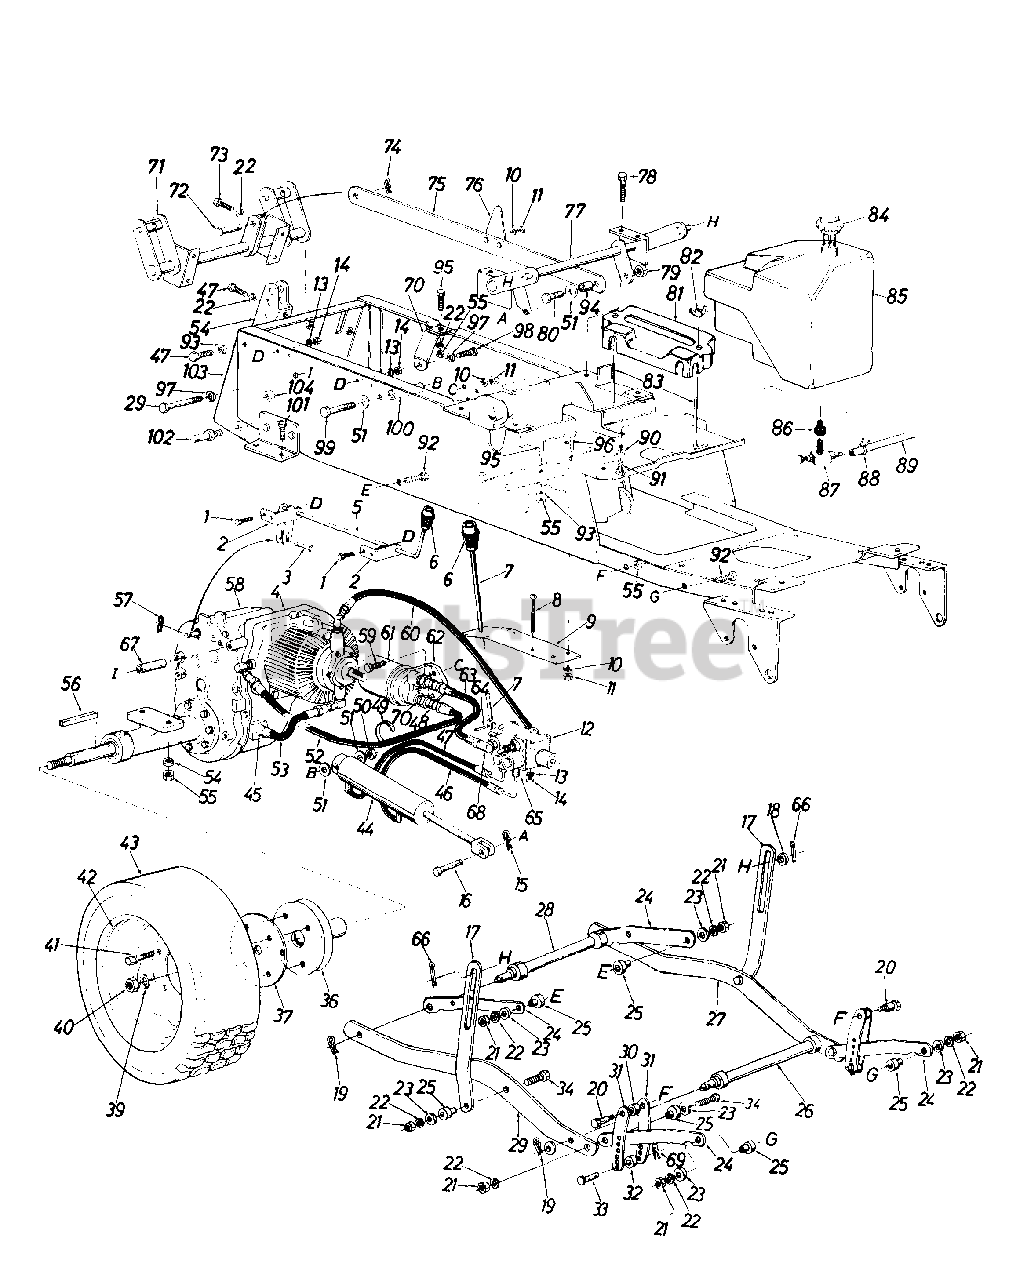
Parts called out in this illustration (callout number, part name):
1	Hex Bolt 1/4-20 x .75" Lg.
4	Hydrostatic Pump Comp.
5	Hi-Lo Control Handle Ass'y.
6	Shift Knob
7	Cylinder Control Handle Ass'y.
8	Truss Mach. Scr. 1/4-20 x 3.00" Lg.
11	Hex Nut 5/16-18 Thd.
12	Valve Ass'y. Comp.
13	L-Wash. 1/4" I.D.
14	Hex Nut 1/4-20 Thd.
15	Hairpin Cotter 1/2" Dia.
16	Clevis Pin 1/2" Dia.
19	Hairpin Cotter
20	Shld. Bolt .498" Dia. x .66"
21	Hex Nut 3/8-24 Thd.
22	L-Wash. 3/8" I.D. - H.D.
23	Fl-Wash. .38" I.D. x 1.00"
26	Cross Shaft Ass'y. - Front
29	Hex Bolt 1/2-13 x 2.75"
30	Collar .50" I.D. x 1.0"
33	Clevis Pin 3/8" Dia.
34	Hex Bolt 3/8-24 x 1.50" Lg. - Grade 5
39	L-Wash. 3/4" I.D.
40	Hex Ins. L-Nut 3/4-16 Thd.
41	Wheel Lug Bolt
44	Hydraulic Cylinder
45	7/8-14 UNF-2A Thd. 5/8 Tube Fitting
46	Valve to Cylinder Hose - 20"
47	Hex Bolt 3/8-16 x .75" Lg. - Grade 5
48	Bushing Reducer 1/2-14 NPTF to 3/8-18 NPTF
49	Cable Tie
50	Hex Jam Nut 1/2-20 Thd.
51	Fl-Wash. .50" I.D. x 1.25
52	Filter Return Hose 24" Lg.
53	Pump Tube Ass'y.
55	Hex Nut 3/8-16 Thd.
56	Sq. Key 1/4" x 1/4" x 2"
57	Hairpin Cotter 1/4" Dia.
58	Peerless Transaxle
59	Hex Bolt 5/16-18 x 1.25"
60	Pump to Valve Hose
61	Fram Filter Ass'y. PH-16
63	Valve to Filter Hose - 8.38"
64	Spring Pin Spiral 1/8" Dia.
65	Flare Adapter
66	Cotter Pin 1/8" Dia. x 1.0"
68	Adapter 9/16-18 to 9/16-18
69	Hairpin Cotter
70	Transmission Brace
73	Hex Scr. 3/8-16 x 1.00" Lg. Grade 5
74	Cotter Pin 1/8" Dia. x 1.25"
79	Hex Cent. L-Nut 1/2-20 Thd.
80	Hex Scr. 1/2-20 x 1.25" Lg.
81	Battery Cover
82	Wing Nut 1/4-20 Thd.
83	Battery Hold Down Rods
84	Gas Tank Cap
85	Gas Tank Ass'y.
86	Bushing
87	Fuel Shut-Off Valve with Screen
88	Gas Line Clamp 1/2"
89	Gas Line 26" Lg.
91	Hex Scr. 1/4-20 x .38" Lg.
92	Hex Scr. 3/8-24 x 1.50" Lg.
93	L-Wash. 3/8" Scr.
94	Push Bar Sleeve
95	Hex Scr. 3/8-16 x 1.00" Lg. - Grade 5
96	Hex Scr. 5/16-18 x .75" Lg.
97	L-Wash. 1/2" Scr.
98	Hex Scr. 1/2-13 x 1.25" Lg.
99	Hex Scr. 1/2-20 x 3-1/2" Lg. - Grade 5
100	Spacer for Cylinder
101	Hex Scr. 3/8-16 x 1.75" Lg.
102	Link Clevis Pin
